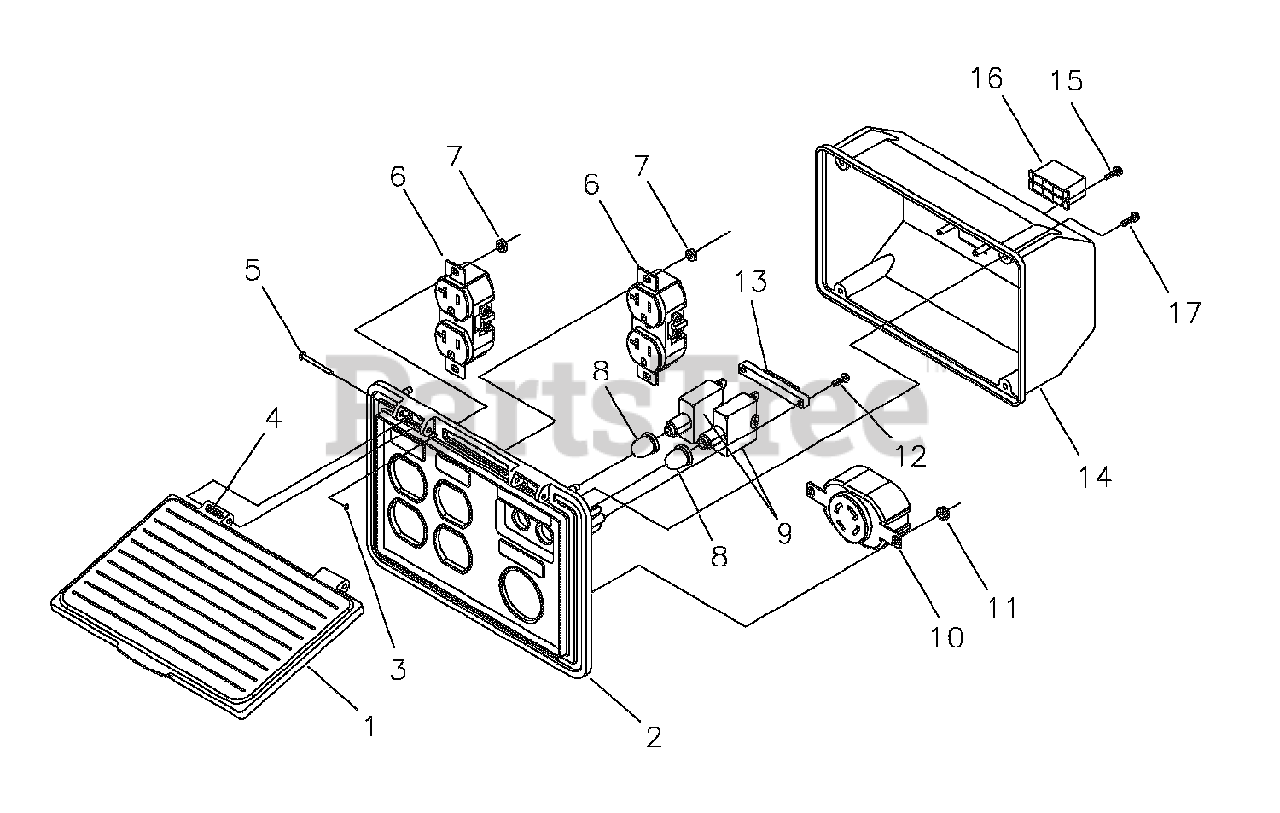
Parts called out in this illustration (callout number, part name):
1	COVER, Lid, Control Panel
2	CONTROL PANEL, Compact
3	CLIP, Hinge Pin Retainer
4	SPRING, Hinge, Pin
5	PIN, Hinge, Cover, Compact
6	OUTLET, 120V, 20A, Duplex
7	NUT, Palnut, Pushnut
8	CAP, Circuit Breaker
9	BREAKER, Circuit
10	OUTLET, 120/240V Locking, 30A
11	NUT, Palnut, Pushnut
13	BAR, Retaining
14	COVER, Back, Control Panel
16	HOUSING, Receptacle
